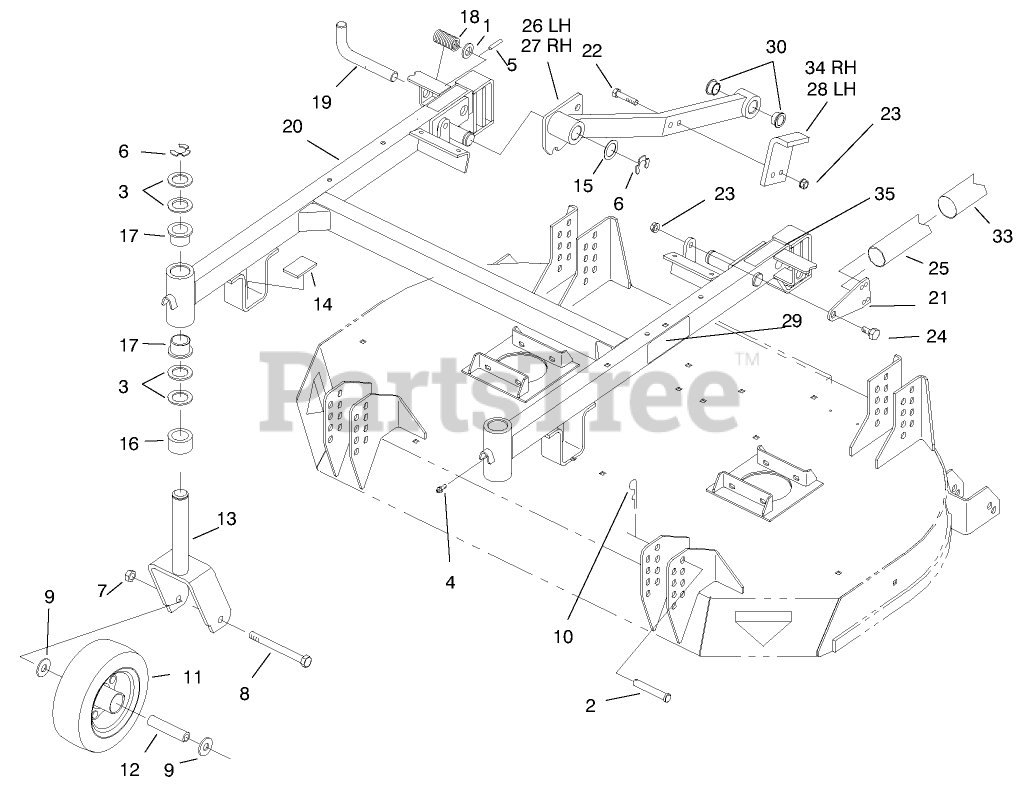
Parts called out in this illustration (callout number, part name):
1	WASHER-THRUST
2	PIN-CLEVIS
3	WASHER-THRUST
4	FITTING-GREASE
5	PIN-ROLL
6	RING-RETAINING
7	NUT-HEX
8	SCREW-HH
9	WASHER-FLAT
10	PIN-HAIR
11	TIRE AND BEARING ASM
12	SPANNER-TIRE
13	Fork
14	CUSHION - RUBBER
15	Washer
16	SPACER-CASTOR
17	BUSHING
18	SPRING-COMPRESSION
19	PIN - PIVOT
20	Frame-Carrier
21	Plate-Spring
22	SCREW-HH
23	NUT-LOCK, NI
24	BOLT-SHOULDER
25	SPRING-EXTENSION
26	Push Arm LH
27	Push Arm RH
28	Stop-Pusharm
29	DECAL - HOC
30	BEARING-FLANGE
33	COVER-SPRING
34	STOP - PUSH ARM,RH R
35	DECAL-WARNING
